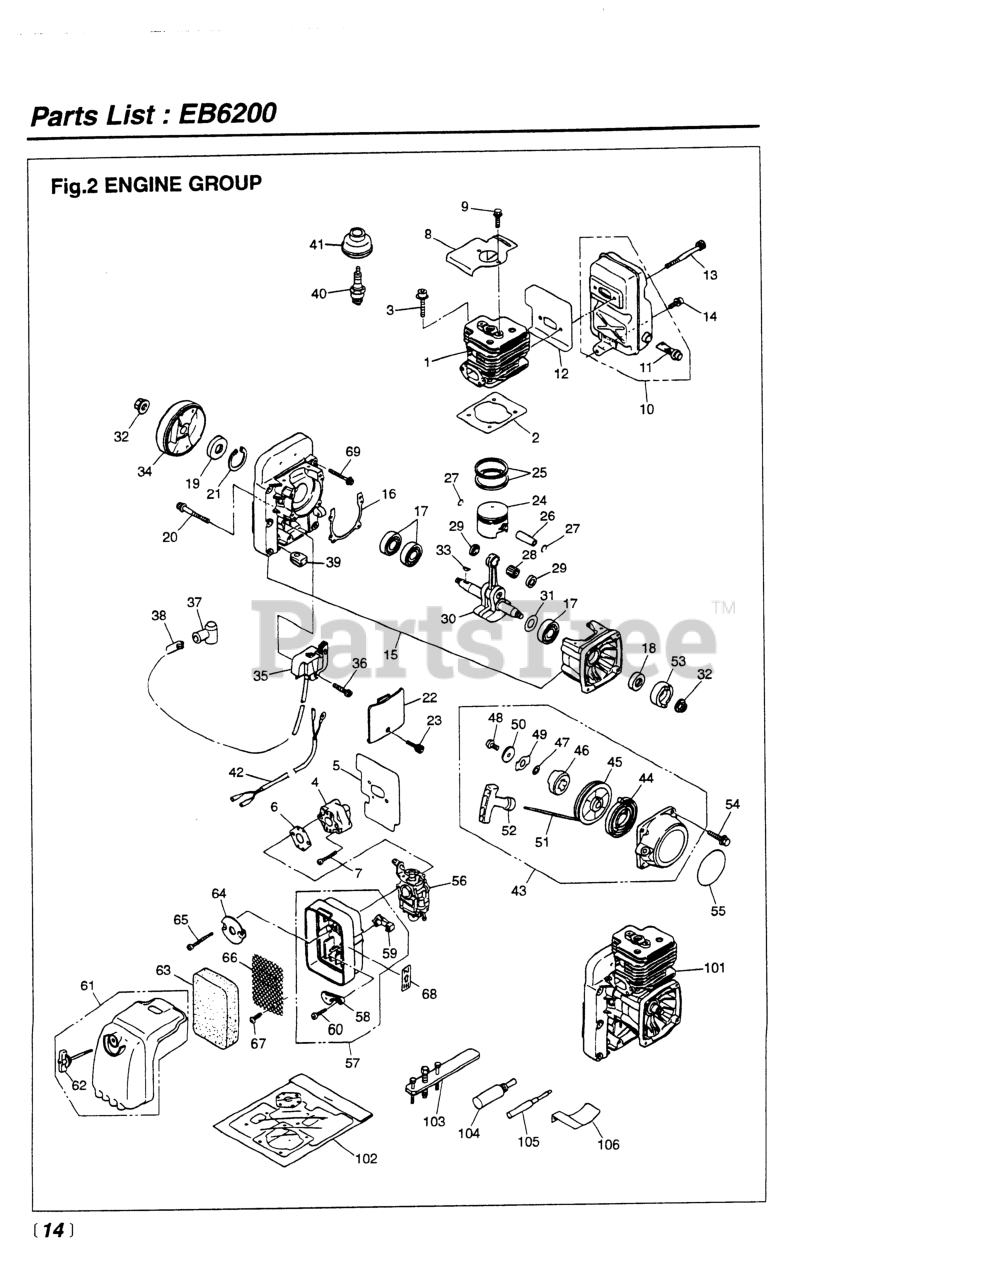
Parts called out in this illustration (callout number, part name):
2	GASKET, BASE
5	GASKET
6	GASKET, CARB (RPLS -13131)
7	SCREW, M5 x 35
8	COVER
9	BOLT, M5 x 10
11	ARRESTER
12	GASKET
13	BOLT, M6 X 70
14	BOLT, M6 X 12
15	CRANKCASE (USE 2750-21101)
16	GASKET
18	SEAL, OIL - STARTER SIDE
20	BOLT, M5 X 30
21	RING, SNAP, M35 X 1.5
22	COVER
23	BOLT, M4 X 16
24	PISTON
25	RING
26	PIN, PISTON
27	RING, SNAP
28	BEARING
29	WASHER (RPLS 1491-41510)
31	SHIM (REPLACES 848-870-G000)
32	NUT, M10
33	KEY
34	ROTOR (USE 2750-71111)
35	COIL ASSEMBLY, IGINITION
36	BOLT, M4 X 16
38	SPRING
39	GROMMET
41	CAP
42	CORD COMP.
44	SPRING (RPLS -75220)
46	DOG
47	WASHER
48	SCREW
49	RETAINER (RPLS 1861-75161)
50	WASHER
51	ROPE
52	KNOB
53	PULLEY (RPLS -75210)
54	BOLT, M5 x 20
55	LABEL (RPLS -75610)
56	CARBURETOR (WYK-73-1)
57	BODY, CLEANER
58	PLATE
59	LEVER
60	SCREW (REPLACES 50030272)
62	KNOB
63	ELEMENT (RPLS -82310)
64	PLATE (REPLACES -82511)
65	SCREW, M5 x 60
66	SCREEN (RPLS -82351)
67	SCREW
68	LABEL
69	BOLT, M6 X 40
102	KIT, GASKET
103	PULLER ASSY
104	STOPPER (TOOL) (RPLS 3320-9641
105	PULLER, PISTON PIN
